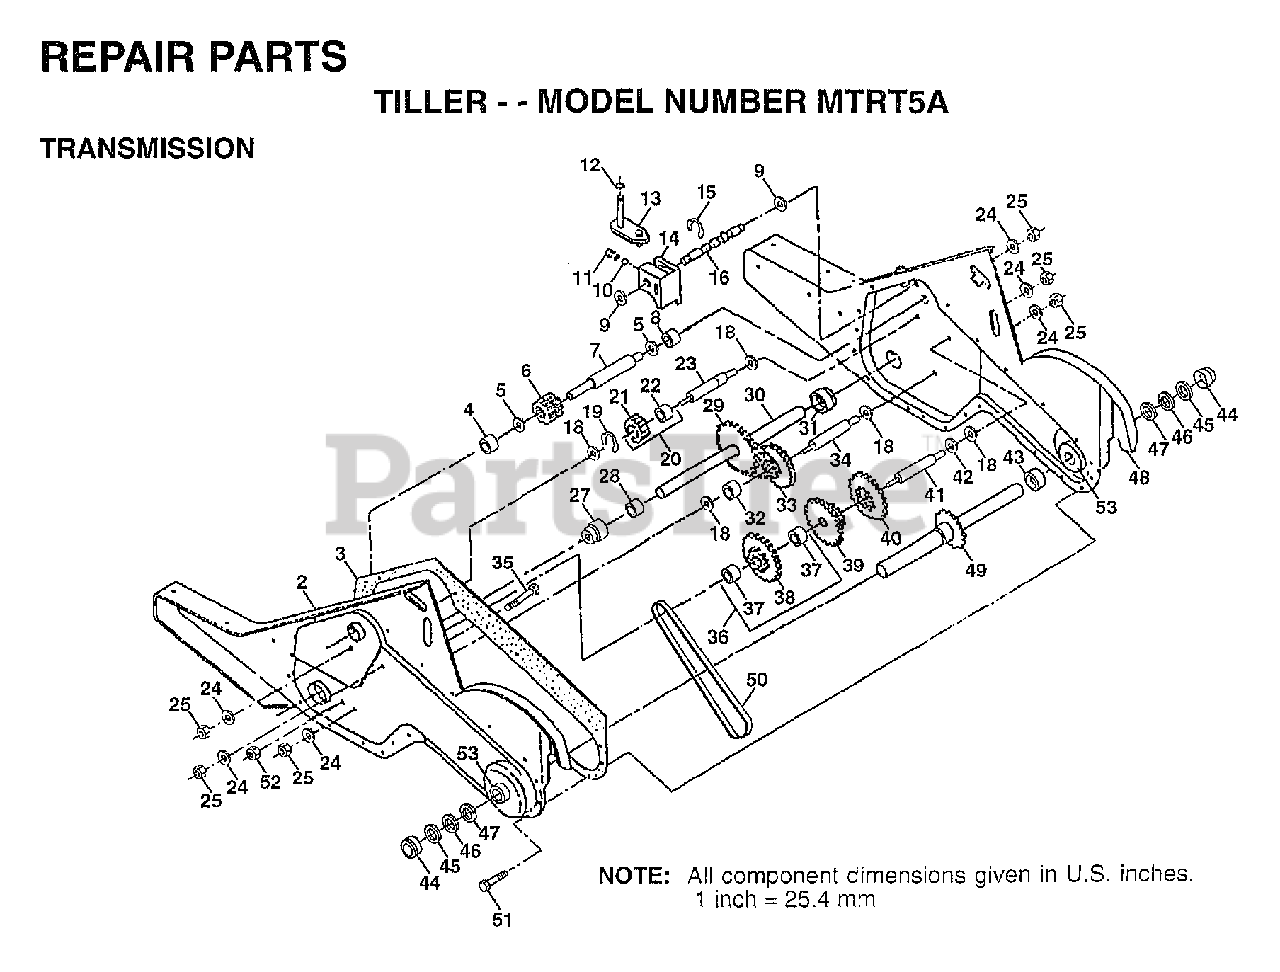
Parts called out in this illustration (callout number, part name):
2	GEARCASE LH W/BRG
3	GASKET TI
4	NEEDLE BRNG LT
5	"T, BEARING"
6	GEAR PINION INPUT
7	"SHAFT.INPUT.""D"""
8	"TI, BEARING"
9	WASHER SEAL CRT
11	SPRING-SHIFT CRT
12	O-RING TI
13	BRACKET ASM SHIFT
14	SHIFT FORK TI
15	KLIP RING
16	SHAFT.SHIFT.4.250
18	WASHER
19	KLIP RING
20	GEAR ASSY CRT
21	GEAR-REV IDLR CRT
22	NEEDLE BEARING TI
23	SHAFT CRT
24	LOCKWASHER
25	NUT.ASF.HEX.7/16
27	BEARING.SHAFT.LH.
28	BUSHING TI
29	CHAIN CRT
30	GROUND SHAFT ASSY
31	BEARING.SHAFT.RH.
32	SPACER TI
33	SPRCKT 8 GEAR CRT
34	SHFT 2ND RED. CRT
35	SCRW WHIZ LOK CRT
36	SPROCKET ASM.
37	BEARING
39	GEAR TI
40	GEAR TI
41	REDUCTION SHFT TI
42	BRNG RACE
43	SPACER TI
44	CUP.FORMED.
45	RING SPIRAL CRT
46	SEAL RING RUBBER
47	OIL SEAL STD
48	GEARCASE RH W/BRG
49	TINE SHAFT
50	CHAIN.50 LINK TI
51	SCREW
52	NUT.HEX.5/16-18
